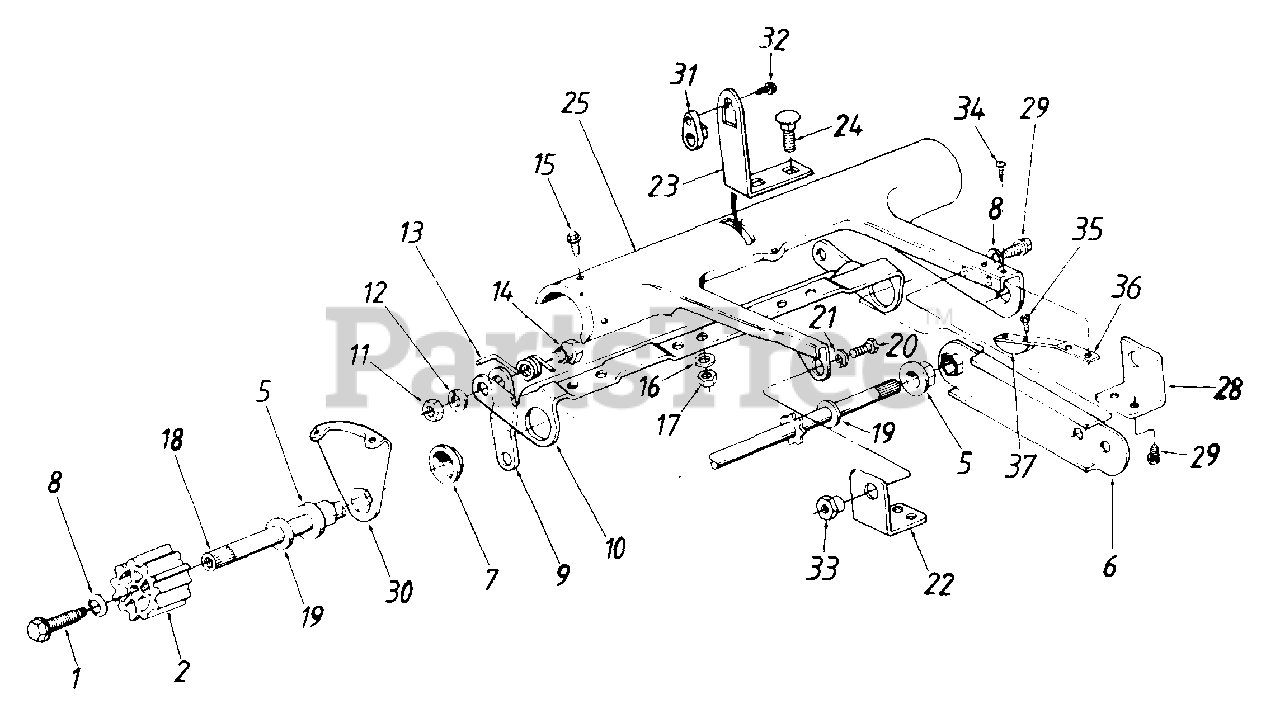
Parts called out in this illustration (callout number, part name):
1	Hex Scr. 1/4-20 x .75" Lg. (Gr. 5)
2	Wheel Drive Pinion
5	Hex Flange Brg..504" I.D.
8	Bell-Wash..265" I.D. x .75" O.O.
11	Hex Nut 5/16-18 Thd.
12	L-Wash. 5/16" I.D.
13	Torsion Spring - R.H.
14	Shoulder Bolt .437" Dia.
15	Hex L-Hd. AB-Tap Scr. 1/4" x 62" Lg.
16	L-Wash. 1/4" I.D.
17	Hex Nut 1/4-20 Thd.
18	Drive Shaft Ass'y.
19	Fl -Wash..531" I.D. x .93" O.D.
20	Hex Bolt 3/8-16 x .5" Lg.
21	L-Wash. 3/8" I.D.
32	Hex B-Tap Scr. #10 x .44" Lg.
33	Shld. Nut .625" Dia. x .165" Lg.
34	Truss Mach. B-Tap Scr. #10 x .5" Lg.
35	Hex B-Tap Scr. #10 x 3/8" Lg.
36	Cantilever Spring
37	Chain Tensioner
